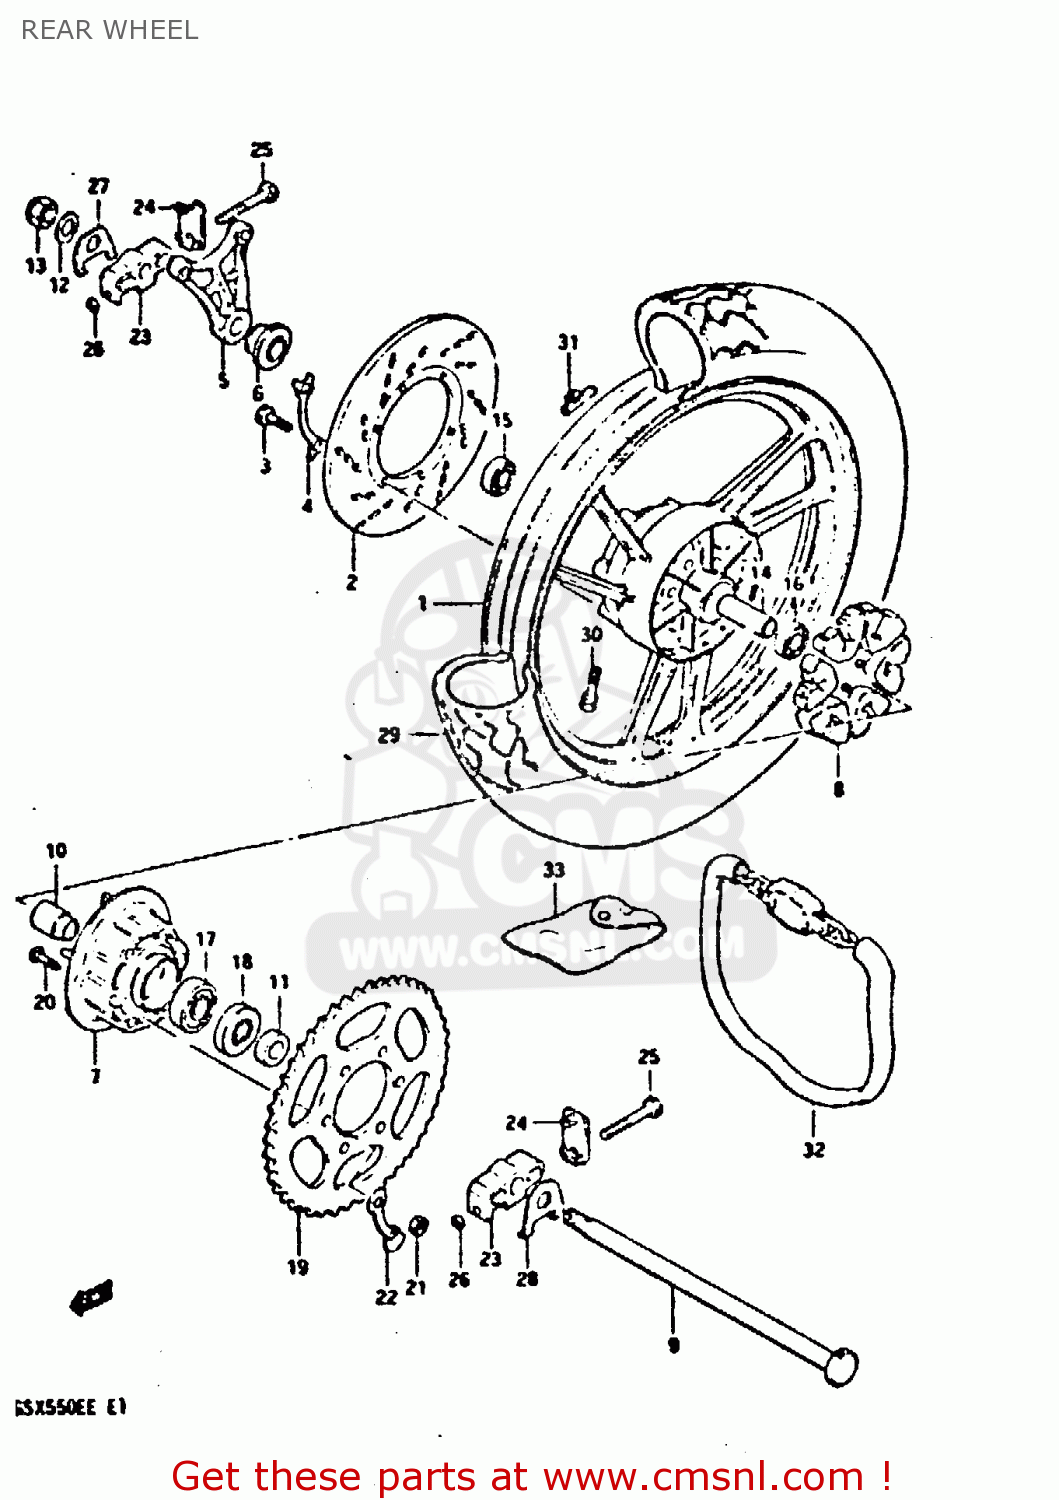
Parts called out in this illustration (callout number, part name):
1	WHEEL,REAR
2	DISC,REAR BRAKE
3	BOLT(8X25)
4	WASHER
5	BRACKET,RR,CALIPER
6	SPACER,REAR AXLE
7	DRUM,REAR SPROCKET MOUNT
8	ABSORBER,RR HUB SHOCK
9	AXLE,REAR
10	SPACER,REAR HUB BEARING
11	SPACER (17X30.5X13.5)
12	WASHER
13	NUT
14	SPACER(17.5X25X81)
15	BEARING
16	BEARING
17	BEARING
18	SEAL,OIL(30.5X52X8)
19	SPROCKET, REAR (NT:46)
20	BOLT(10X35.5)
21	NUT
22	WASHER
23	BODY,CHAIN ADJUSTER
24	PLATE,CHAIN ADJUSTER
25	BOLT,CHAIN ADJUSTER
26	E RING
27	WASHER,CHAIN ADJUSTER RH
28	WASHER,CHAIN ADJUSTER
29	TIRE
30	VALVE,TIRE
31	BALANCER,WHEEL
32	CHAIN LOCK ASSY
33	BAG,CHAIN LOCK
